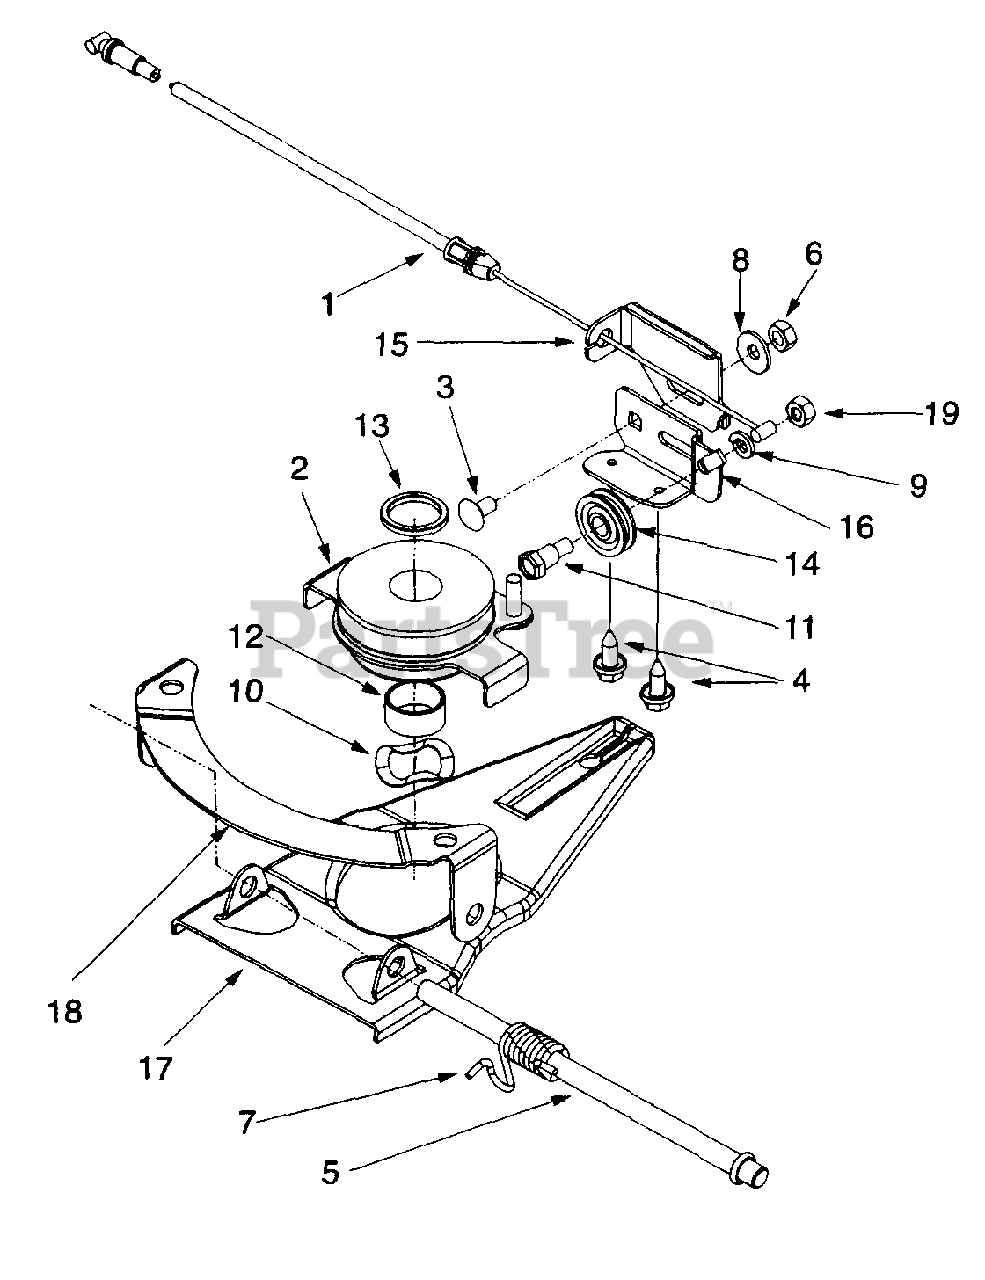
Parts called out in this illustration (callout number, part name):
1	Six-Speed Cable
2	Pulley Ass'y. Multi Speed
3	Carr. Scr. 1/4-20 x .50
4	Scr. AB 1/4-14 x .625
5	Pivot Shaft
6	Nut 1/4-20
7	Torsion Spring
8	Bell Washer .265 x.75 x.062
9	Lock Washer 1/4 Reg. Duty
10	Wave Washer 1.38 x .88 x .029
11	Shld. Scr. .340 x .350 x 1/4-20
12	Slev. Spacer .88 I.D. x 1 O.D. x .48
13	Slev. Spacer .88 I.D. x 1.13 O.D. x .12
14	Roller Cable
19	Hex Nut 1/4-28
